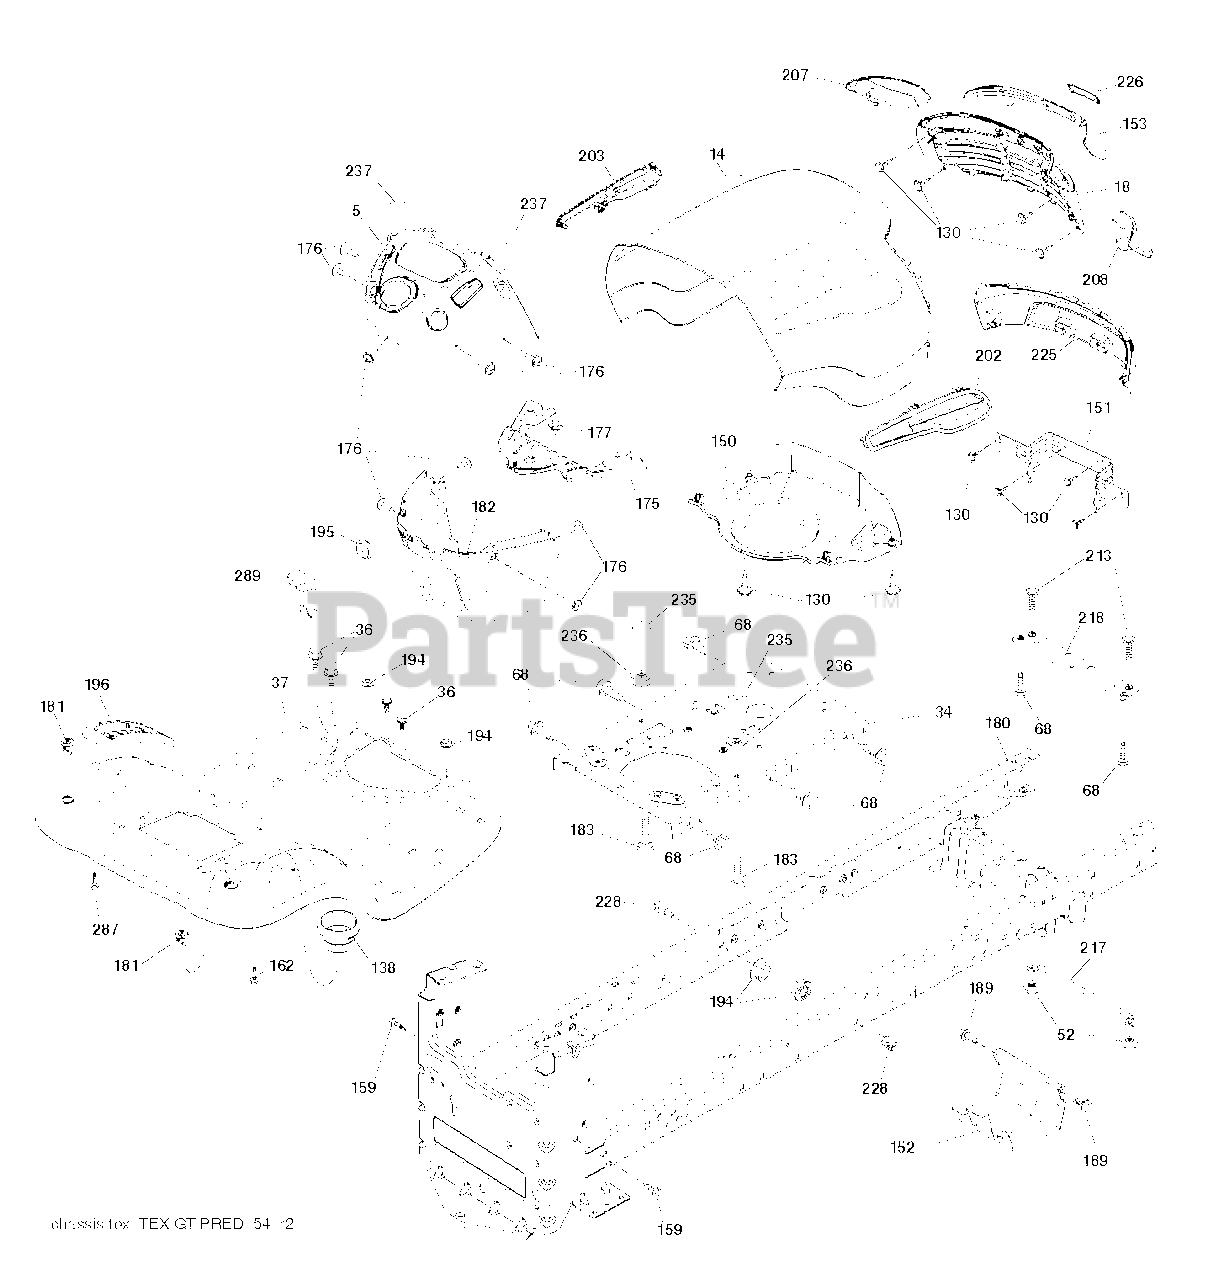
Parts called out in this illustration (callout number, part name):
36	SCREW 5/16"
52	LOCKNUT
130	SCREW.#10 X 0.750.BOS THREAD
138	CUPHOLDER.TL.TEX.BLACK
152	SHIELD BROWNING
159	SCREW, 3/8-16X3/4
162	SCREW.HI-LO.CONSOLE
175	PLATE.CROSSMEMBER.HUSQ
176	SCREW.#10-24X5/8.RN.QU
177	BUSHING,STEERING
180	CHASSIS
181	FEND/FTRST.PCH.CPH.NFW
182	DASH.LOWER.COMMON.12V.ADAPTOR
183	BOLT.5/16-18X1-1/4 FULL THD
189	SCREW
194	NUT LOCK HEX FLANGE 5/16-18
195	PLUG.HOLE.DASH.LOWER.12V.BLK
196	CONSOLE.ASM.DECKLFT.BL/RBT.TLT
213	BOLT
217	ROD.PIVOT.HOOD
218	X-PIECE.HOOD.STOP.NON/
228	STUD.FASTNER.W/ANTI-ROTATE
235	SPACER FENDER
236	NUT.CENTERLOCK.5/16-
237	PLUG.MOUNT.CARGO.BLK
289	PLUG.N/CRUISE.COMMON.YT/GT.BLK
